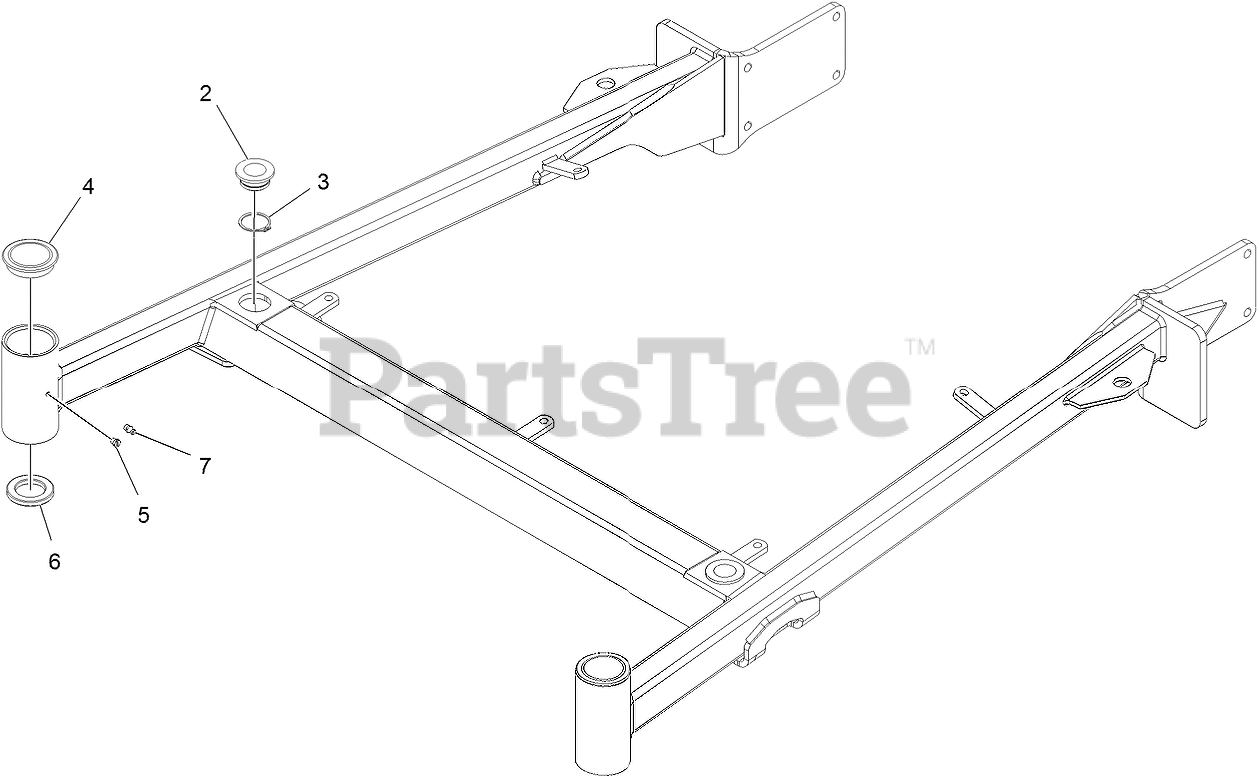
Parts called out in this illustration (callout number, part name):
2	BUSHING-DECK
3	RING-RETAINING
4	CAP-GREASE
6	SEAL-GREASE
7	FITTING-GREASE
